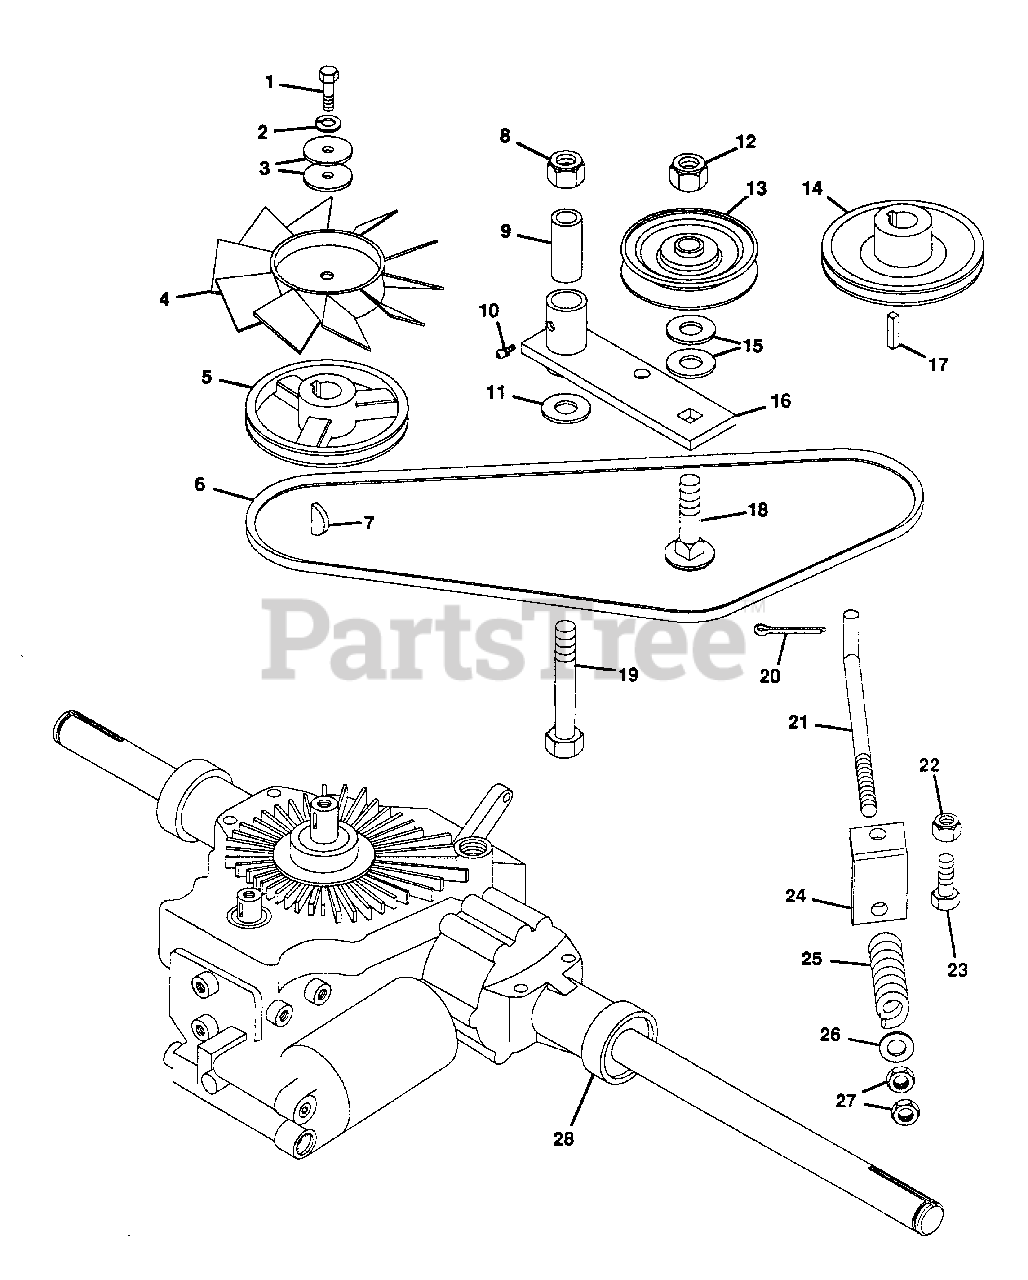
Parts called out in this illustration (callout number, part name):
1	BOLT, HEX 1/4-20X1.25
2	WASHER, LOCK 1/4 REG.
3	WASHER, FLAT .265X1.250X.063
4	FAN
5	PULLEY, DRIVE
6	BELT
7	KEY, WOODRUFF .187X.625 HRD #61
8	NUT, LOCK 1/2-13
9	SPACER, .850X.546X2.50
10	FITTING, LUBE 1/4-28
11	WASHER, FLAT .500X1.250X.083
12	NUT, LOCK 1/2-13 E.T.
13	PULLEY, IDLER
14	PULLEY
15	WASHER, FLAT .531X1.062X.095
16	WELDMENT, IDLER ARM
17	KEY, SQUARE .250X1.250
18	BOLT, 1/2-13X1.75 RD HD SQ NK
19	BOLT, HEX 1/2-13X3.50
20	PIN, COTTER .094X.75
21	ROD, IDLER
22	NUT, LOCK 3/8-16
23	BOLT, HEX 3/8-16X1.00
24	SUPPORT, SPRING
25	SPRING, COMP. 1X.78X338 LB/N
26	WASHER, FLAT .406X.812X.065
27	NUT, HEX 3/8-24
28	TRANSAXLE, HYDROSTATIC
